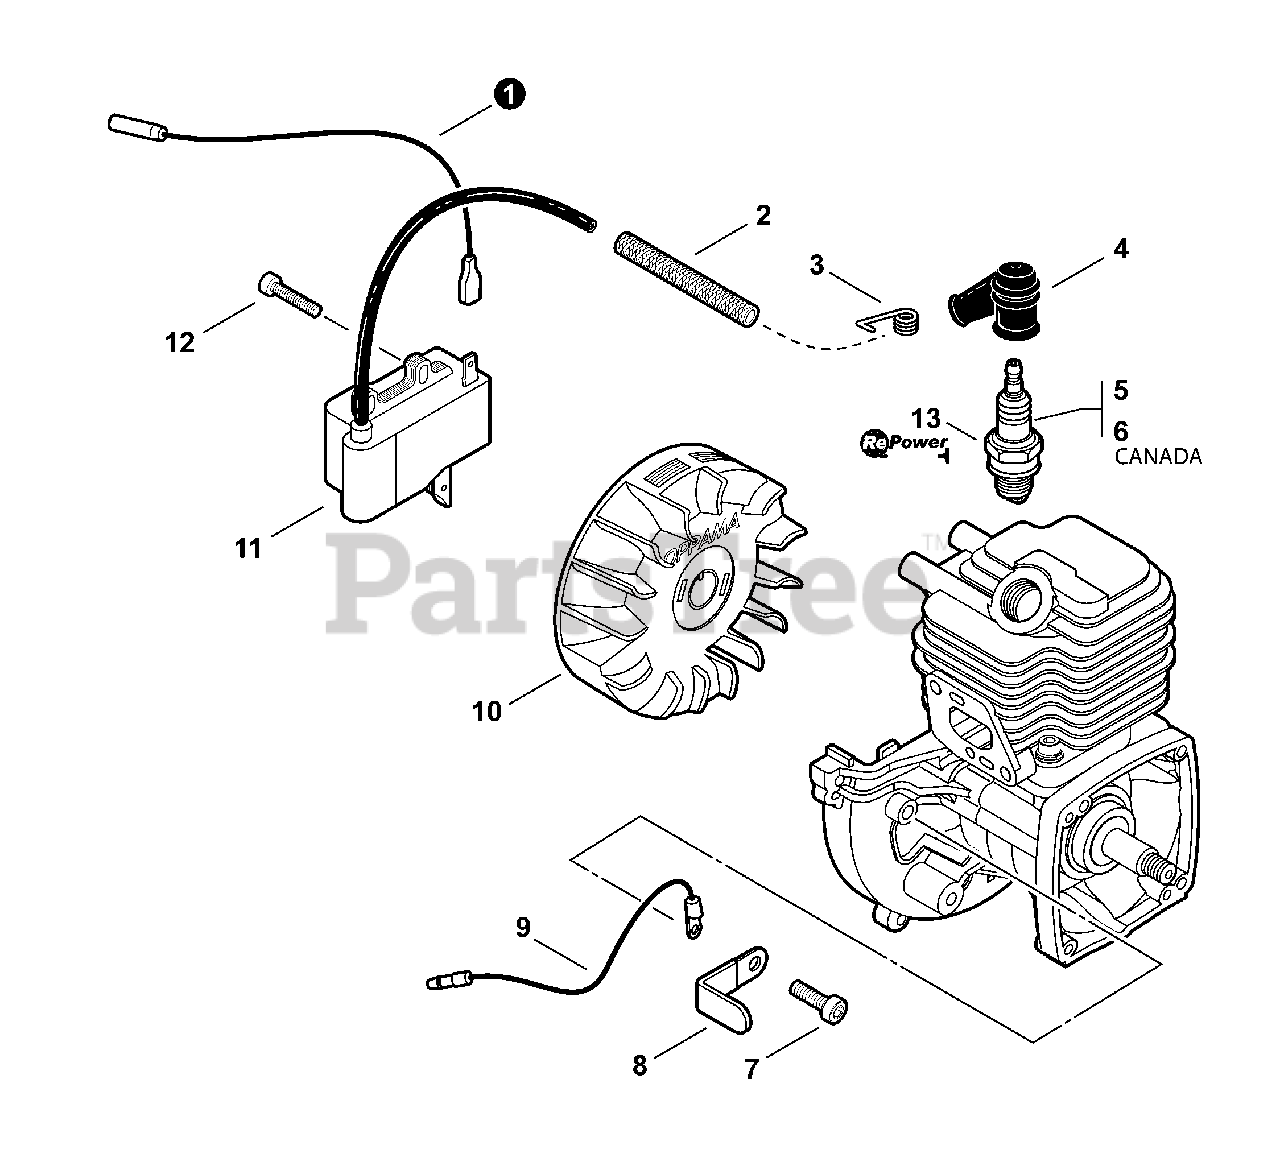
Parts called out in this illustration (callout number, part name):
1	LEAD - IGNITION
2	TUBE, INSULATOR
3	TERMINAL, SPARK PLUG CAP
4	CAP, SPARK
5	SPARK PLUG -- BPM8Y
6	SPARK PLUG -- BPMR8Y
7	SCREW - 5×10
9	LEAD - GROUND
10	FLYWHEEL
11	COIL, IGNITION
12	SCREW - 4×20 -- TORX
13	RePower TUNE-UP KIT
